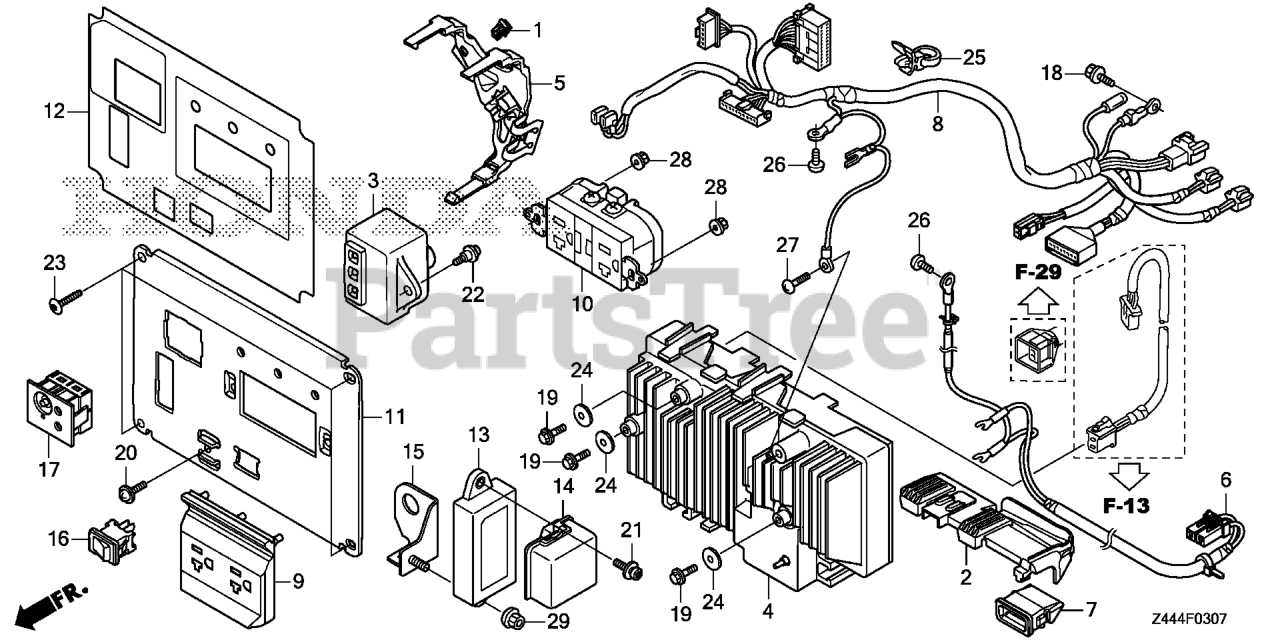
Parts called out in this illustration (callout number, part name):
1	CLIP, TUBE
2	RUBBER B, TANK MOUNTING
3	SPARK UNIT
4	INVERTER UNIT
5	BRACKET, INVERTER HARNESS
6	SUB-WIRE HARNESS ASSY.
7	COVER, CONNECTOR
8	WIRE HARNESS ASSY., CONTROL
8	HARN, CONTL WIRE
9	COVER, RECEPTACLE (20A-125V)
10	RECEPTACLE (20A-125V) (GFCI)
11	PANEL, CONTROL
12	MARK, CONTROL PANEL
13	SENSING UNIT (CO)
14	COVER, SENSING UNIT PROOF (CO)
15	BRACKET, SENSOR UNIT (CO)
16	SWITCH, AUTO-THROTTLE (OTAX)
17	LED ASSY., INDICATER
18	BOLT, FLANGE (5X10)
19	BOLT, FLANGE (5X12)
20	SCREW, PAN (5X12) (GROUND CABLE)
21	BOLT-WASHER (5X15) (TORX)
22	SCREW, PAN (5X13)
23	SCREW, TAPPING (5X16) (TORX)
24	WASHER, PLAIN (20MM)
25	BAND (100MM) (BLACK)
26	SCREW, PAN (5X8)
27	SCREW, PAN (5X10)
28	NUT, FLANGE (4MM)
29	NUT, FLANGE (5MM)
